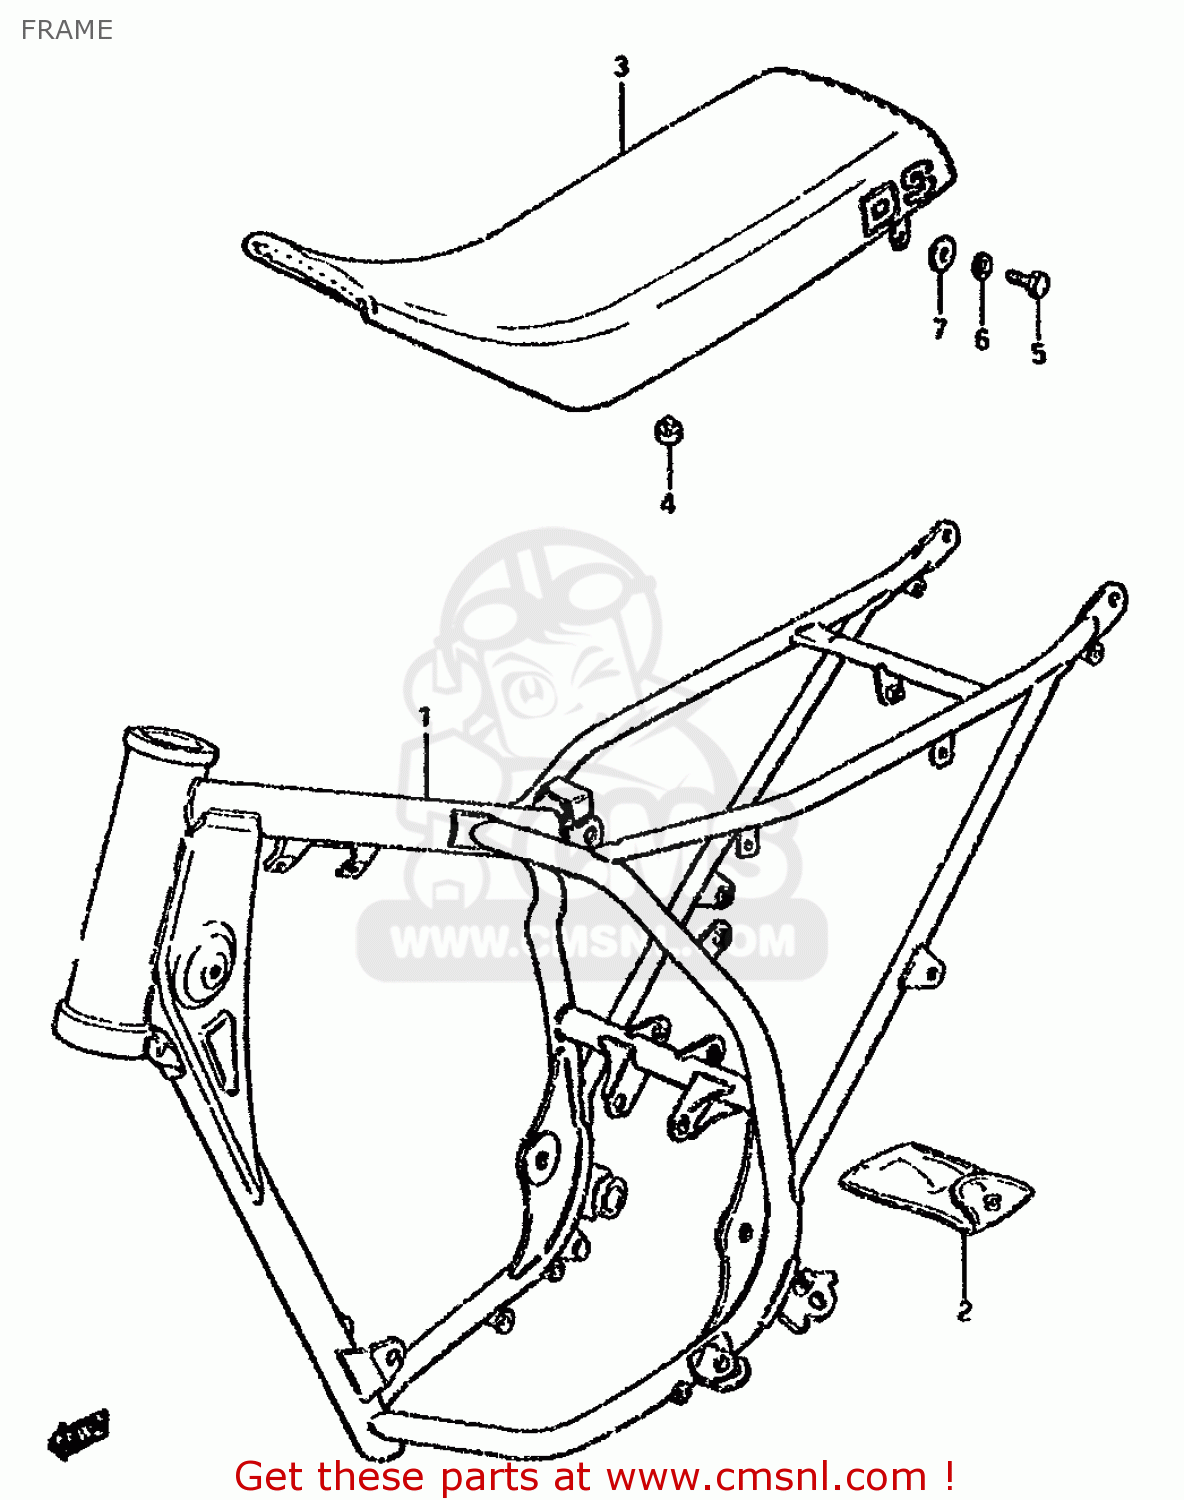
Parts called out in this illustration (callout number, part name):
1	FRAME
2	TOOL ASSY
3	SEAT ASSEMBLY
4	CUSHION
5	BOLT
6	WASHER,LOCK
7	WASHER (6.5X18X1.6)
